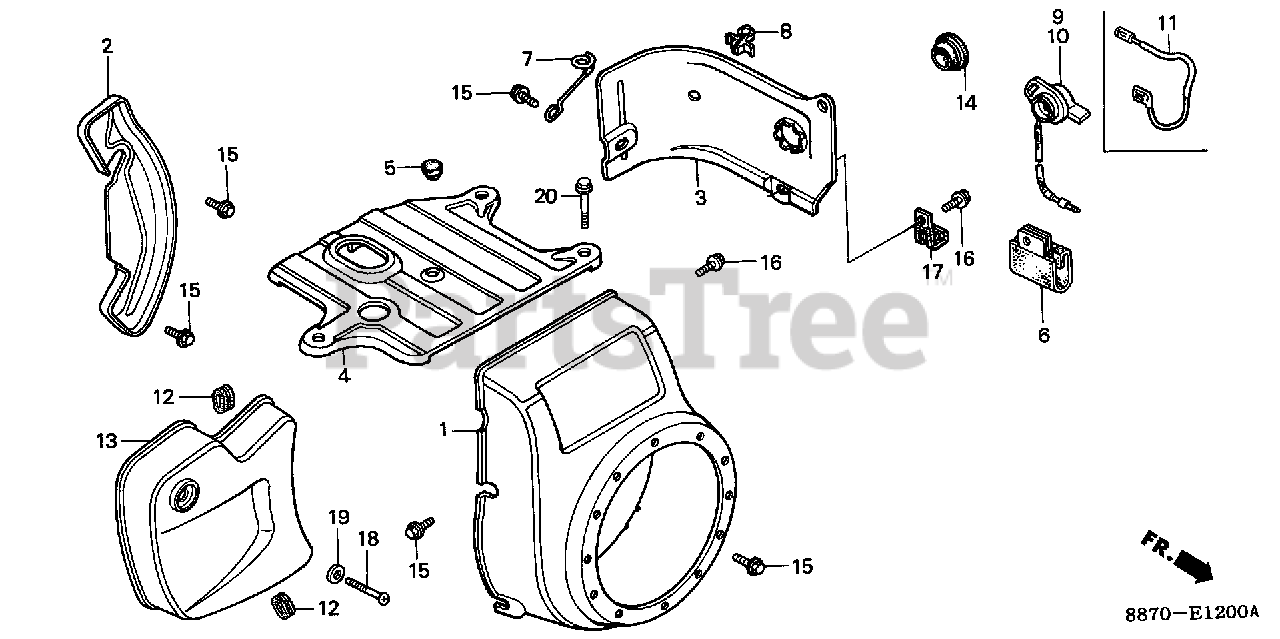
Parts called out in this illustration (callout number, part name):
1	COVER, FAN *R280* (POWER RED)
2	PLATE, SIDE
4	COVER, TOP
5	GROMMET, TOP COVER
8	CLIP, IGNITION WIRE (8MM)
9	SWITCH ASSY., ENGINE STOP
15	BOLT, FLANGE (6X12) (CT200)
16	BOLT, FLANGE (6X12) (CT200)
17	CLIP, WIRE
